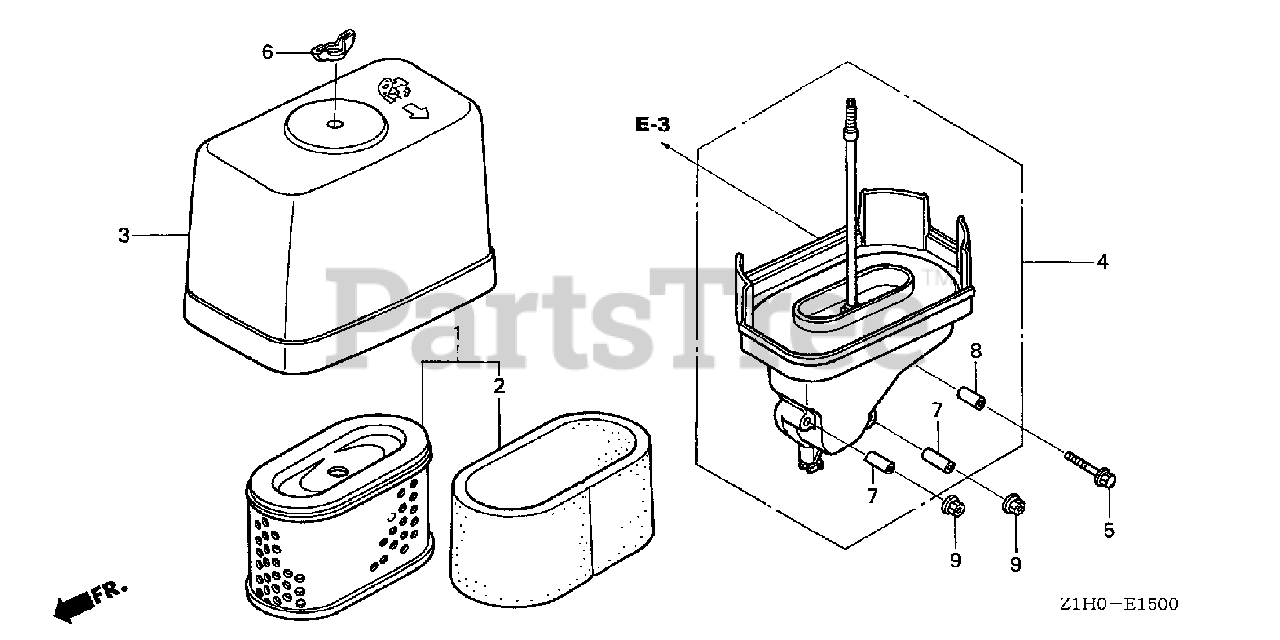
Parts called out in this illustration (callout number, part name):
1	ELEMENT, AIR CLEANER (PLASTIC BASE)
2	FILTER (OUTER)
3	COVER, AIR CLEANER
4	ELBOW, AIR CLEANER
5	BOLT, FLANGE (6X35) (CT200)
6	NUT, TOOL BOX SETTING
7	COLLAR, AIR CLEANER
8	COLLAR, AIR CLEANER
9	NUT, FLANGE (6MM)
